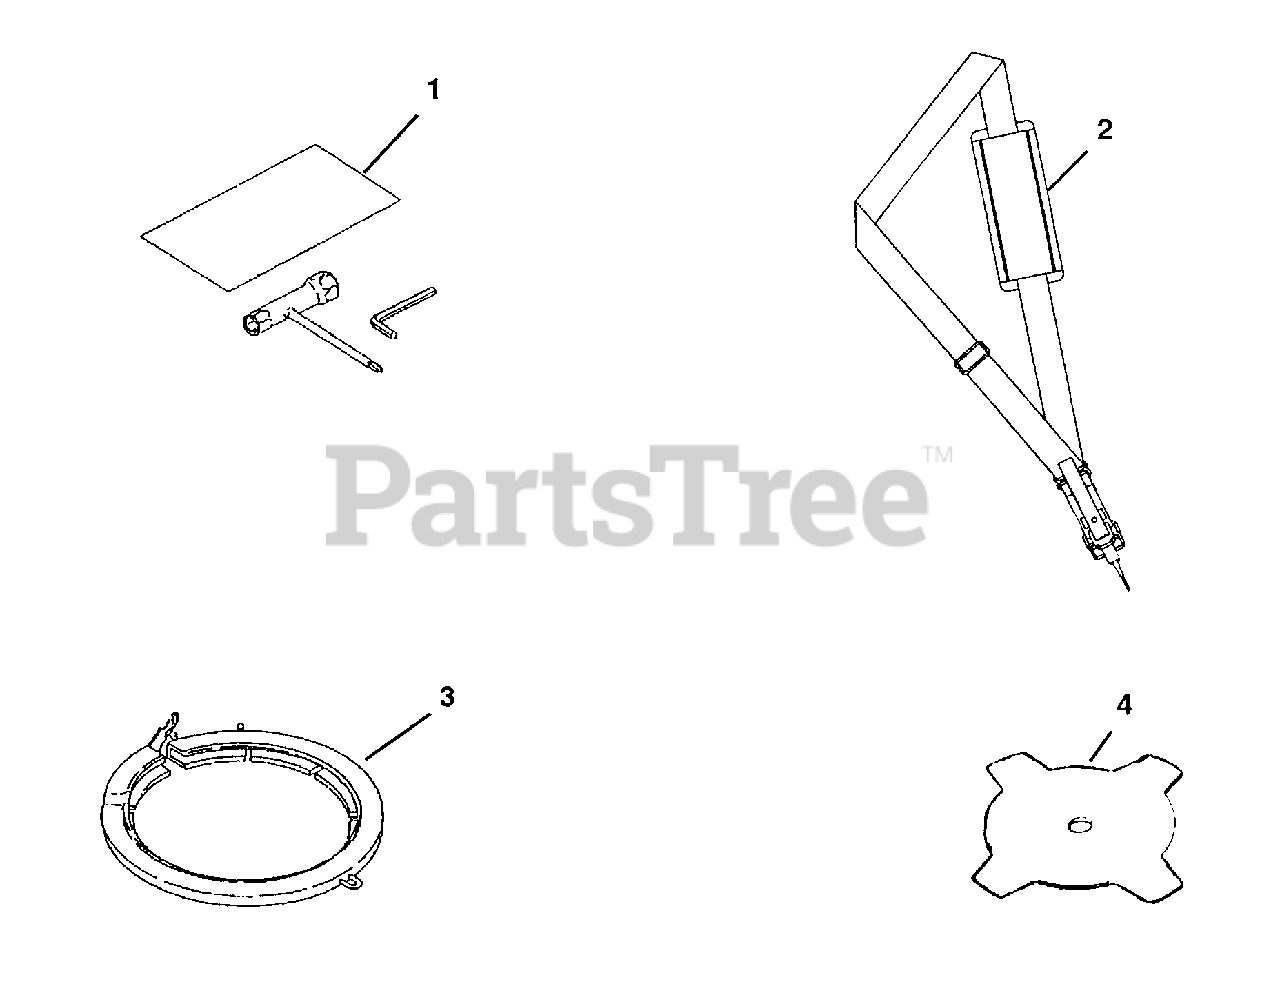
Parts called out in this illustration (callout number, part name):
1	TOOL KIT
3	BLADE COVER
4	QUAD BLADE
